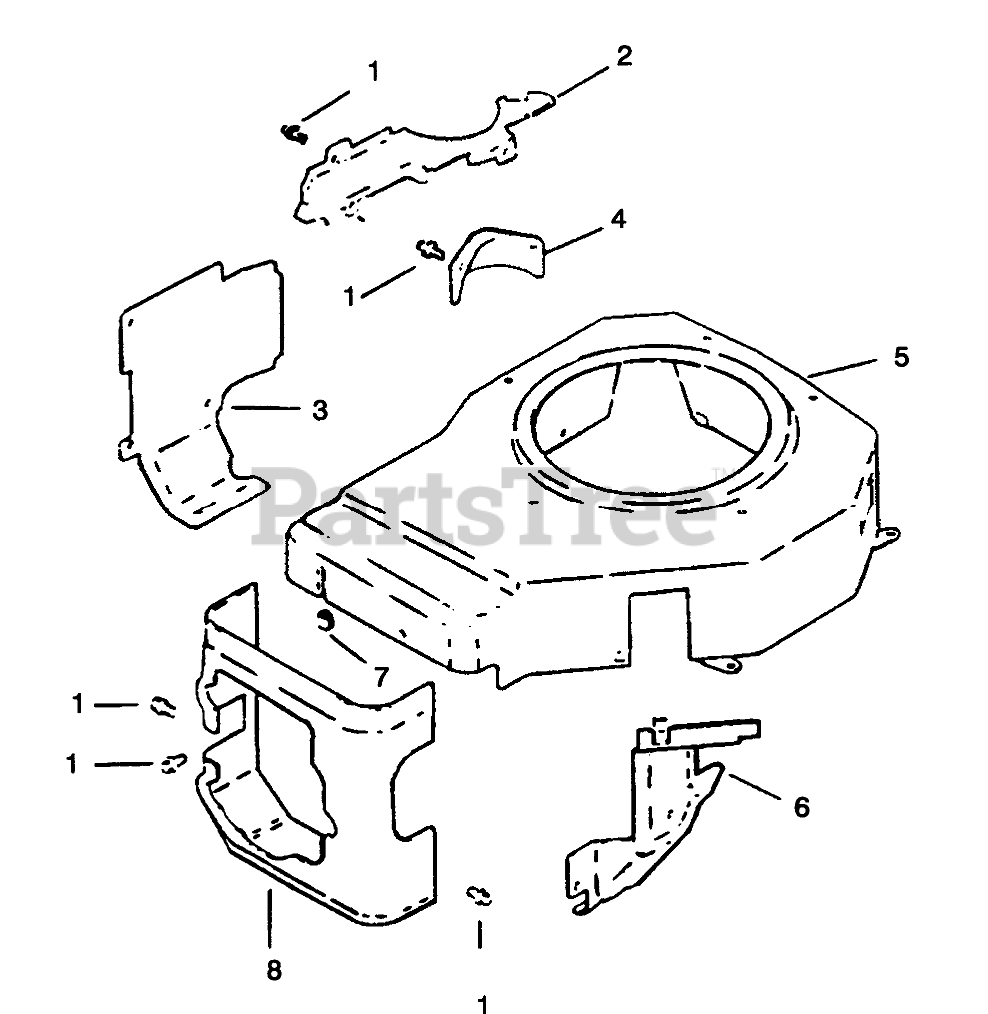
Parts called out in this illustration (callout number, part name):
1	Blower Housing & Baffle Group
1	Screw
2	Plate-Blower Housing
3	Baffle-Cylinder Barrel
4	Cover-Starter
5	Housing-Blower
6	Baffle-Carburetor
7	Grommet-Blower Hsg
8	Baffle-Cylinder Head
